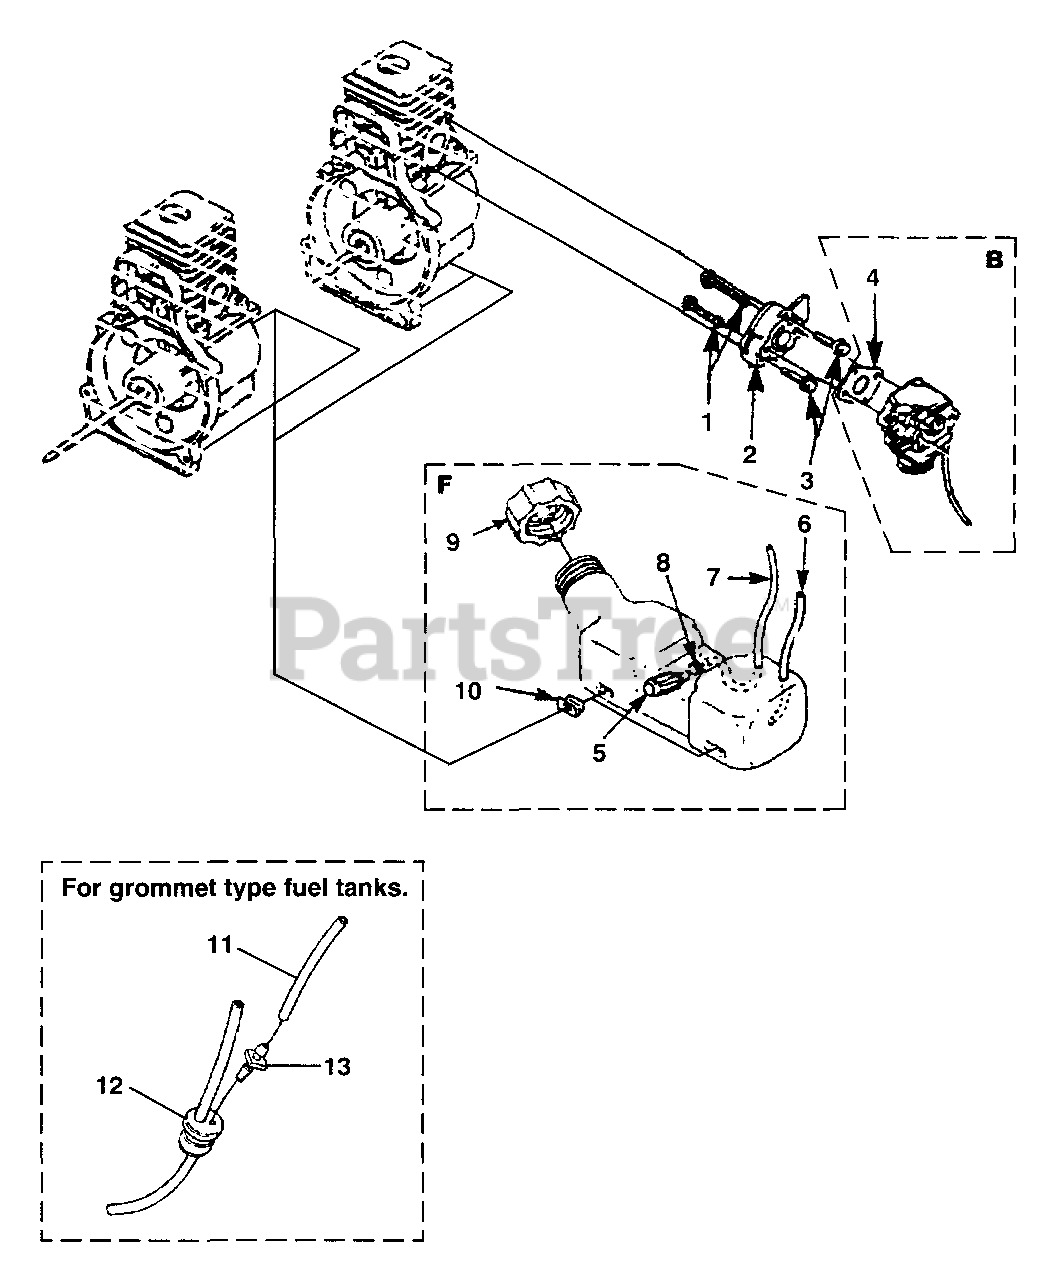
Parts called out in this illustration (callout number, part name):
1	SCREW - Machine (10-24 X 2-1/4")
2	HEAT DAM
3	SCREW - Taptite (10-24 X 1")
4	GASKET - Carburetor
5	FILTER Fuel
6	TUBING - Rubber (8")
7	TUBING - Rubber (8")
8	CLAMP - Wire
9	FUEL CAP
10	BUMPER - Rubber
11	TUBING - Rubber (3 X 3/4")
12	GROMMET w/Tubing
13	FITTING - Fuel
B	CARBURETOR KIT
F	FUEL TANK
